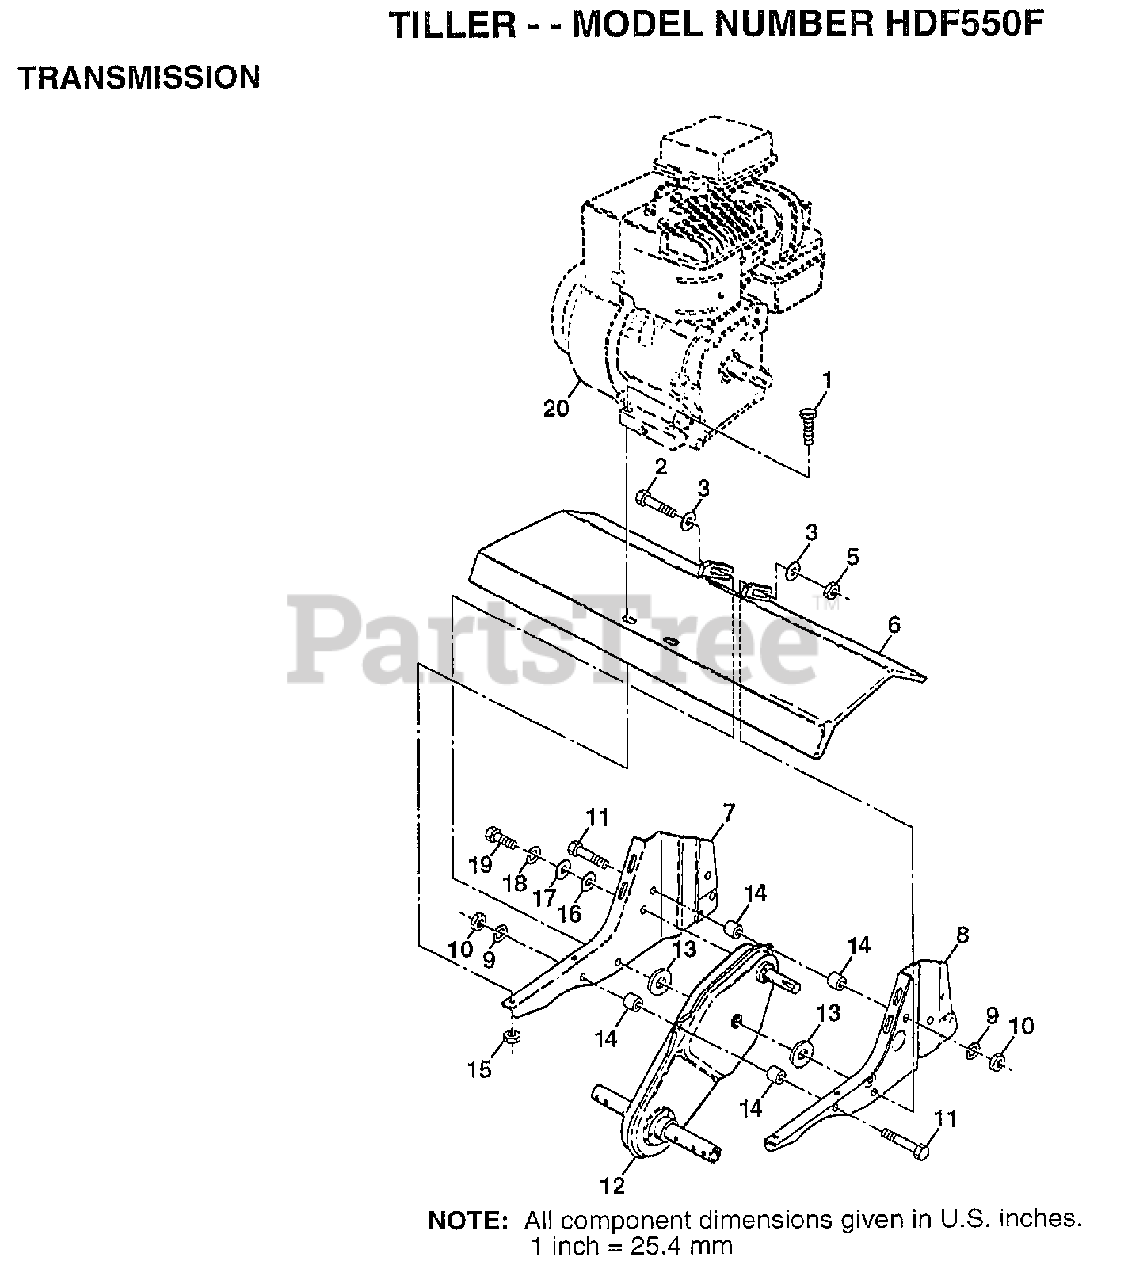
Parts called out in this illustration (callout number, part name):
1	BOLT.HEX.5/16-1.5
2	BOLT HEX 3/8-16
3	WASHER
5	NUT
6	SHIELD TINE
8	ENGINE BRKT LH TI
9	LOCKWASHER
10	NUT.HEX.5/16-18
14	SPLIT SPACER RT
16	WASHER
17	WASHER
18	LOCKWASHER
19	BOLT
